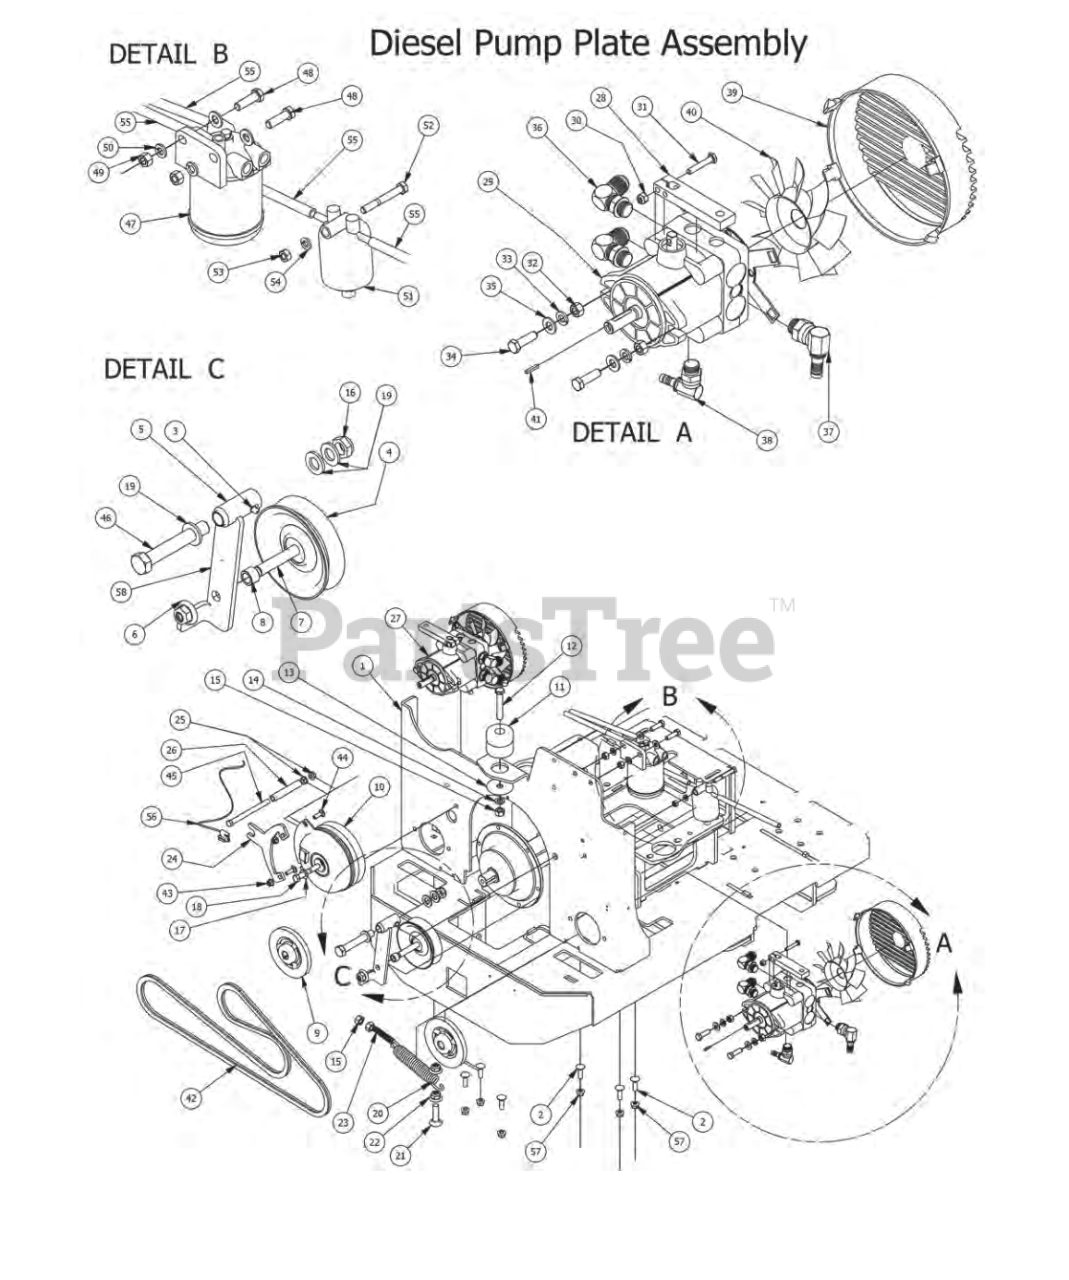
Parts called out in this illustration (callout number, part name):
1	Pump Plate Diesel
2	3/8" x 1 1/4" Carriage Bolt
3	1/4" Drive in Grease Fitting
4	4 3/4" Idler Pulley
5	Pump Idler Bracket only for 61" Deck
6	1/2-13 Nylon Flange Nut-Orange
7	1/2" x 3" Hex Bolt
8	1/2 x 1/2 Spacer
9	5" Pump Pulley
10	Clutch Assembly for Diesel
11	Armor Plated Mount-Rear Mount
12	1/2" x 3" Hex Bolt
13	Snubbing Washer
14	1/2" Lock Washer
15	1/2" Hex Nut
16	5/8" Nylock (1/2 Jam)
17	7/16" Lock Washer
18	7/16" x 2 3/4" Fine Thread Bolt
19	630 ID x 1.122 OD x .142 THK Plastic Washer
20	Deck Idler Spring
21	1/2 x 2" Carriage Bolt
22	1/2-13 Nylon Flange Nut-Orange
23	1/2-13 x 2-1/2 All Thd Stud
24	Diesel PTO Engager Holder
25	3/8" Flange Nut
26	3/8 hose 4" long
27	PR Pump W/Fan Left -1100cc Diesel
29	PR Pump with Fan and Cover Right -1100cc Diesel
30	1/4" Nylock Nut
31	1/4" x 1 1/2" Bolt
32	3/8" Hex Nut
33	3/8" Lock Washer
34	3/8" x 1 1/2" Hex Bolt
35	3/8" Flat Washer
36	6801-LL-8-8 Fitting - Compact Diesel
37	90 Degree Fitting 1/2" x 3/4" 4601-8-8
38	90 Degree Fitting 3/8" X 9/16"-4601-6-6
39	Fan Guard 7" Fits Compact Diesel Only
40	Hydro Fan Diesel 28hp Only
41	5mm x 1.25" Key
42	Pump Belt 28Hp Diesel
43	5/16" Flange Nut
44	5/16" x 1" Carriage Bolt
45	3/8-16 x 5 Hex Bolt - Grade 5
46	5/8" x 4" Hex Bolt 61" Deck only
47	Fuel Filter
48	3/8" x 1 1/4" Hex Bolt
49	3/8" Hex Nut
50	3/8" Lock Washer
51	Caterpillar Fuel Bowl Kit
52	5/16" x 2 1/2" Bolt
54	5/16" Lock Washer
55	5/16" fuel line hose
56	Clutch Pigtail
57	3/8" Nylock Flange Nut
58	Pump Idler Assembly Components 3,4,5,6,7,8, only 1" Deck
